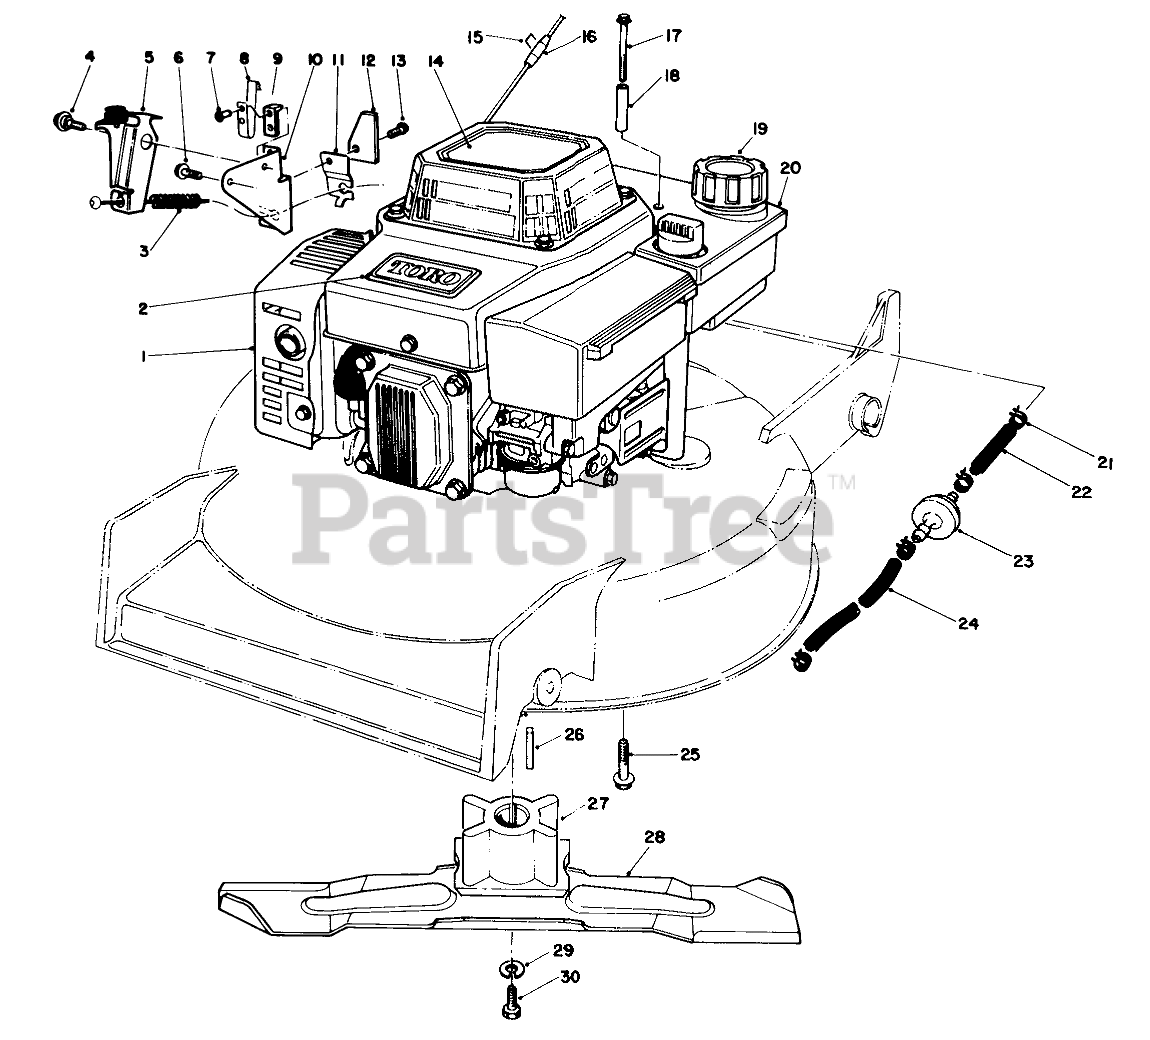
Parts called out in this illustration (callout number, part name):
1	Engine
2	TORO LOGO PLT
3	COMPRESSION SPRING
4	Screw-Shoulder
5	BRAKE PLATE ASM
6	THO FORM SCREW M6 X 1
7	RIVET-PLASTIC
8	STRAP-GROUND
9	Strap-Insulation
10	Plate-Mounting
11	CABLE CLAMP
12	STOP-GROUND STRAP
13	SCREW
14	DECAL-HV INT'L
15	Staple
17	THRD FORMING SCREW
18	TUBULAR SPACER
19	GAS CAP ASM
20	TANK ASM
21	CLAMP-FUEL LINE
22	LINE-GAS
23	FILTER-FUEL
24	HOSE-FUEL
25	SCREW-HWHTF
26	KEY-SQUARE
27	Retainer Blade
28	BLADE-21in
29	WASHER-LOCK
30	SCREW-BLADE
